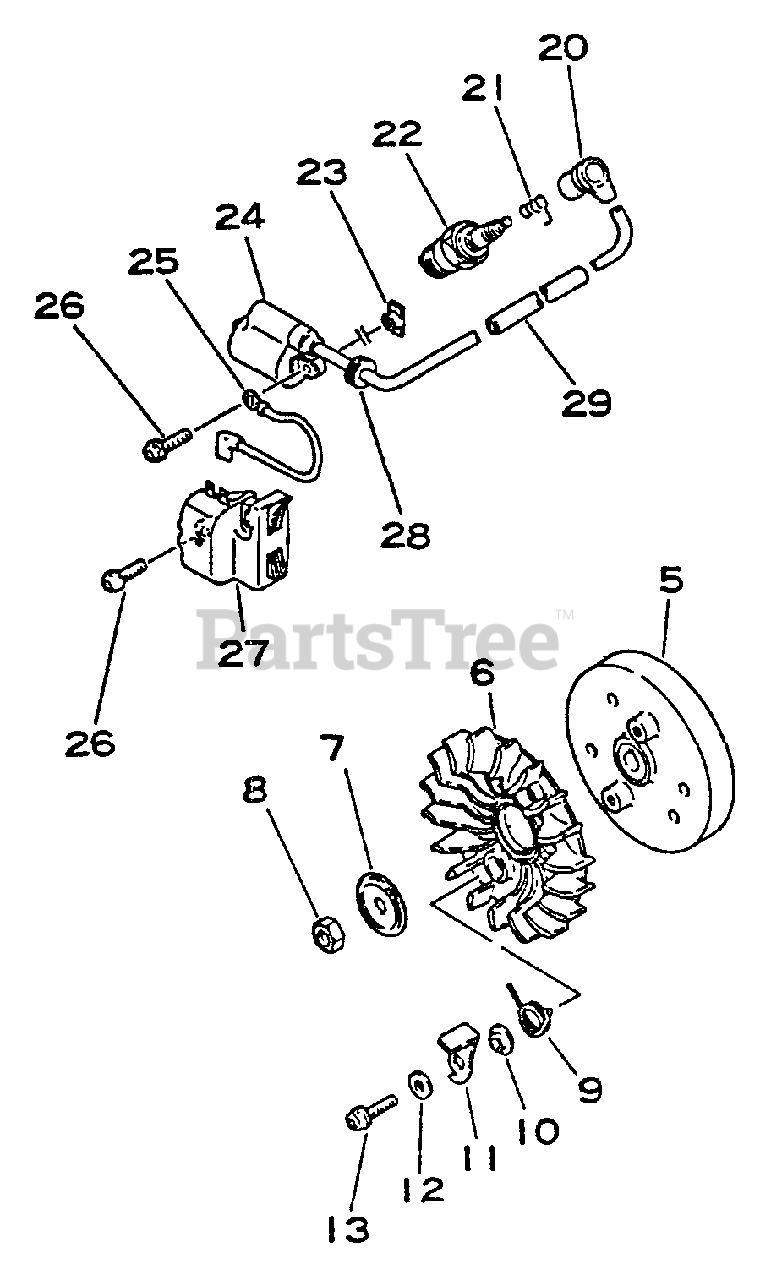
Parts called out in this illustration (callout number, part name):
5	FLYWHEEL
6	FAN
7	WASHER - CUP
9	SPRING, RETURN
11	PAWL, STARTER
12	WASHER - 5
13	SCREW - 5X14
20	CAP, SPARK PLUG
21	TERMINAL, SPARK PLUG CAP
22	SPARK PLUG -- CJ-6Y
24	COIL, IGNITION
26	SCREW - 4X20
27	COIL, IGNITION
29	TUBE
